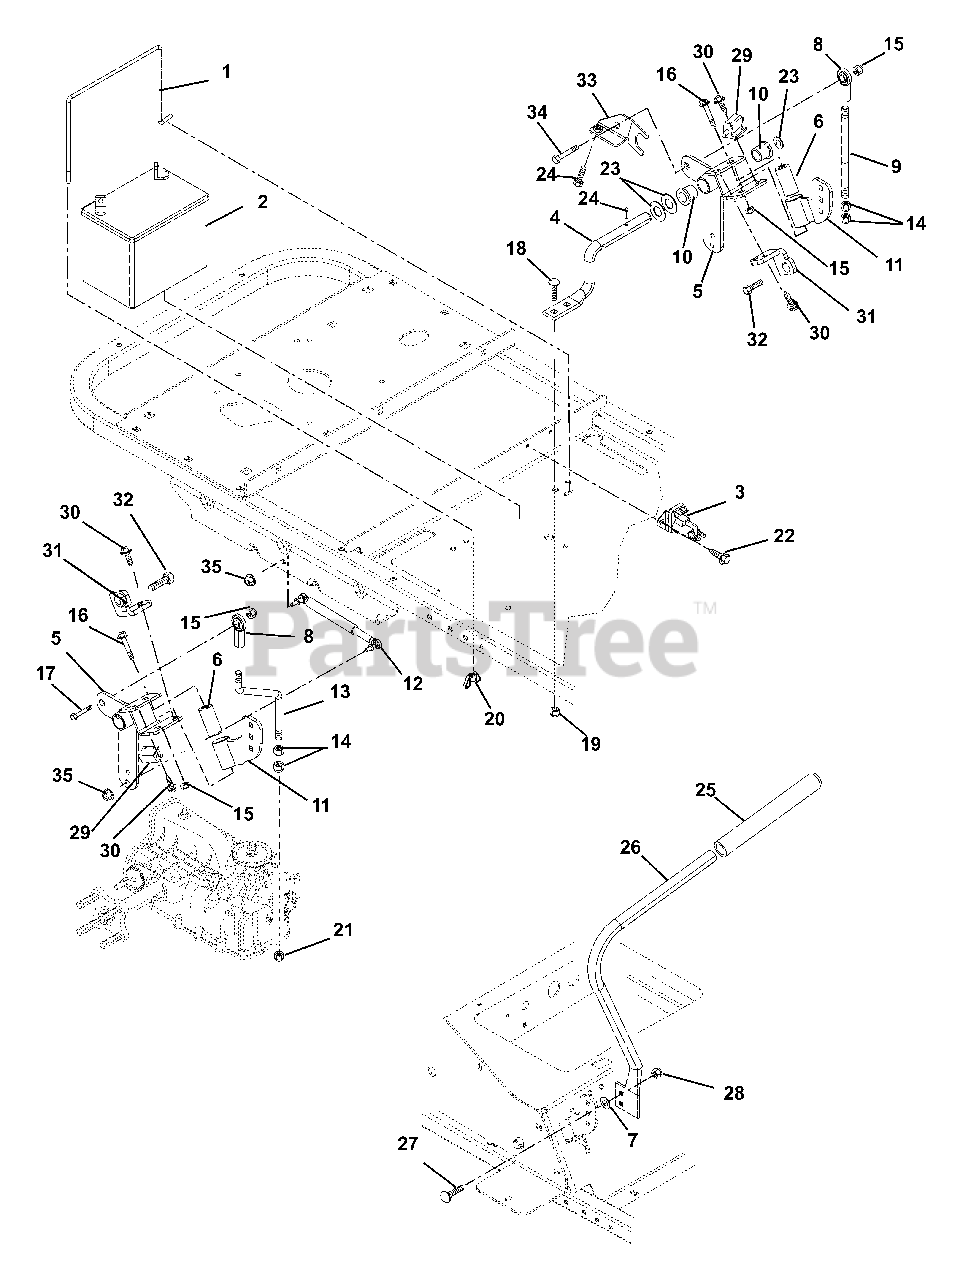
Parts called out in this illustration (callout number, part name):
1	BATTERY ROD
2	BATTERY, 300 CCA 10U1L
3	SOLENOID
4	ROD PIVOT
5	WMT, CONTROL
6	BSHG, SPCR .502X.997X2.03 PM
7	@WSHR-LK-EXT.326X.599X.031YWZC
8	ROD END, 1/2 RH
9	ROD-TRANSAXLE LH
10	BUSHING-1"X.75"X1"
11	WELDMENT, HANDLEBAR RH
13	ROD-TRANSAXLE RH
14	NUT-JAM .50-20 GR2 YWZC
15	NUT-LK-TOP-FLG .50-13 YWZC
16	@BLT-HEX .50-13X3.00 GR5 YWZC
17	@BLT-HEX .50-13X1.75 GR5 YWZC
18	BLT-RDHDSQNK .38-16X1.00 G5YZ
19	@NUT-LK-NYL-FLG .38-16 YWZC
20	NUT-LK WING .250-20 YWZC
21	NUT-LK-JAM-NYL .50-20 GR2 YWZC
22	@SCR-TAP .25-20X.37 HWH YWZ TR
23	WSHR-FL-STL .754X1.000X.032 YZ
24	PIN-ROLL .188X1.13
26	HANDLEBAR WLDM'T RH
27	BLT-RDHDSQNK.31-18X.88 GR5YWZC
28	@NUT-LK-NYL-FLG .31-18 YWZC
29	SWITCH- DOUBLE POLE N.O./N.O.
30	@SCR-TAP 10-24X.50 HWH TR YWZC
31	WMT, HANDLE STOP
32	SCR-SKH .25-20X1.25 PL
33	WMT, REVERSE STOP
34	@BLT-HEX .38-16X1.25 GR5 YWZC
35	NUT, TOP LOCK FLG 8X1.25 YWZC
